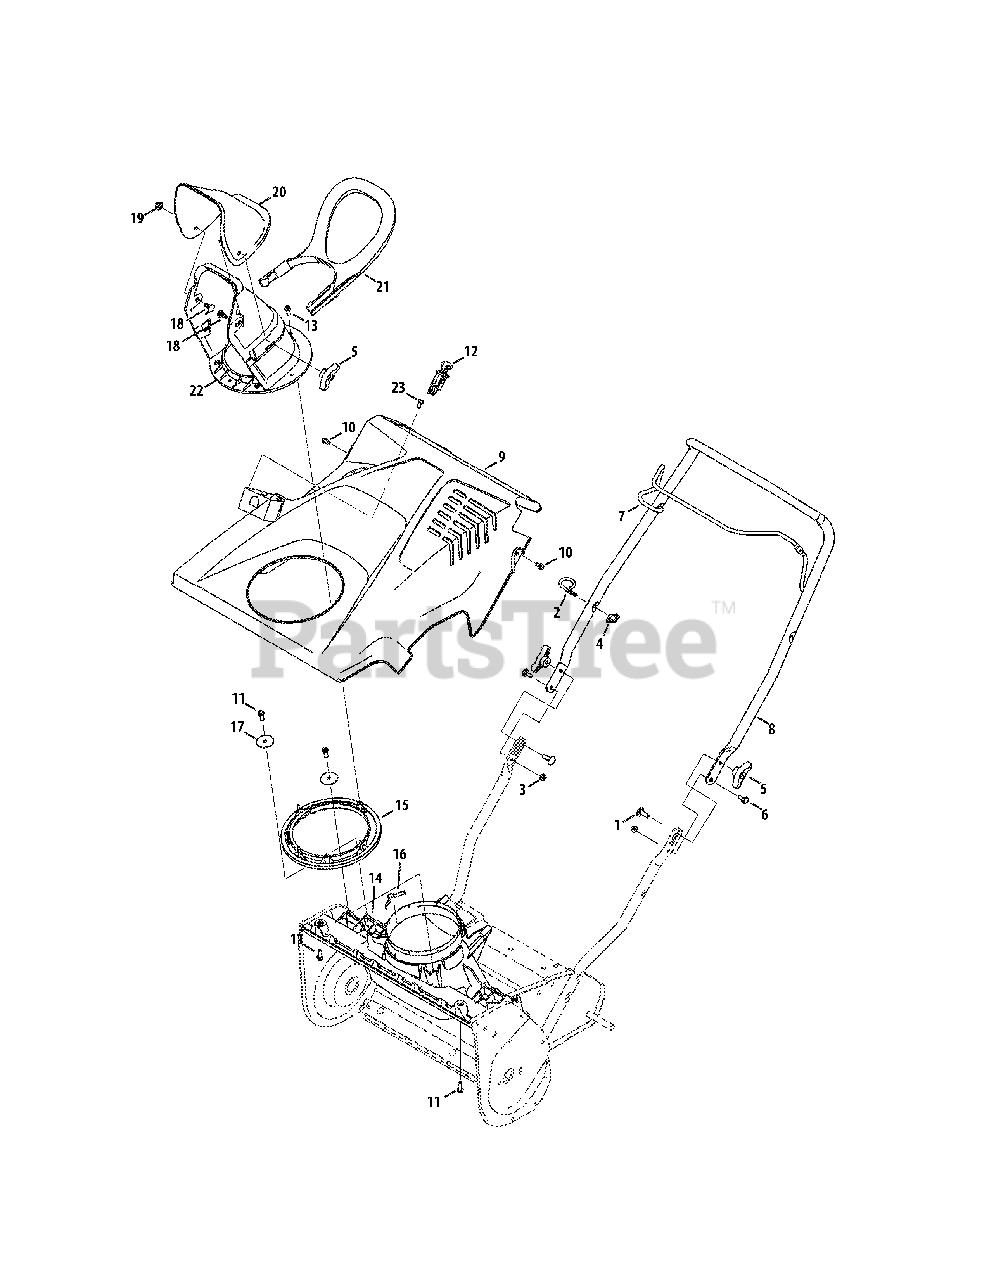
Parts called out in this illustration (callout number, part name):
1	Carriage Bolt, 5/16-18 x 1.00
2	Eye Bolt, 1/4-20
3	Flange Lock Nut, 1/4-20
4	Knob Handle
5	Wing Knob
6	Shoulder Screw, .375 x .148 x 1/4-20
7	Auger Bail
8	Upper Handle
9	Top Cover (Black w/o electric start)
10	Hex Washer Screw, 1/4-20 x .625
11	Screw, Hi-Lo:1/4-15, 0.75
12	Ignition Switch Assembly
13	Hex Washer Screw, 1/4 x .750
14	Chute Adapter
15	Chute Ring
16	Chute Adjustment Spring
17	Flat Washer, .28 x 1.5 x .066
18	Carriage Bolt, 5/16-18 x .750
19	Flange Lock Nut, 5/16-18
20	Upper Chute
21	Chute Handle
22	Lower Chute
23	Hex Washer Screw, 1/4-15 x .50
